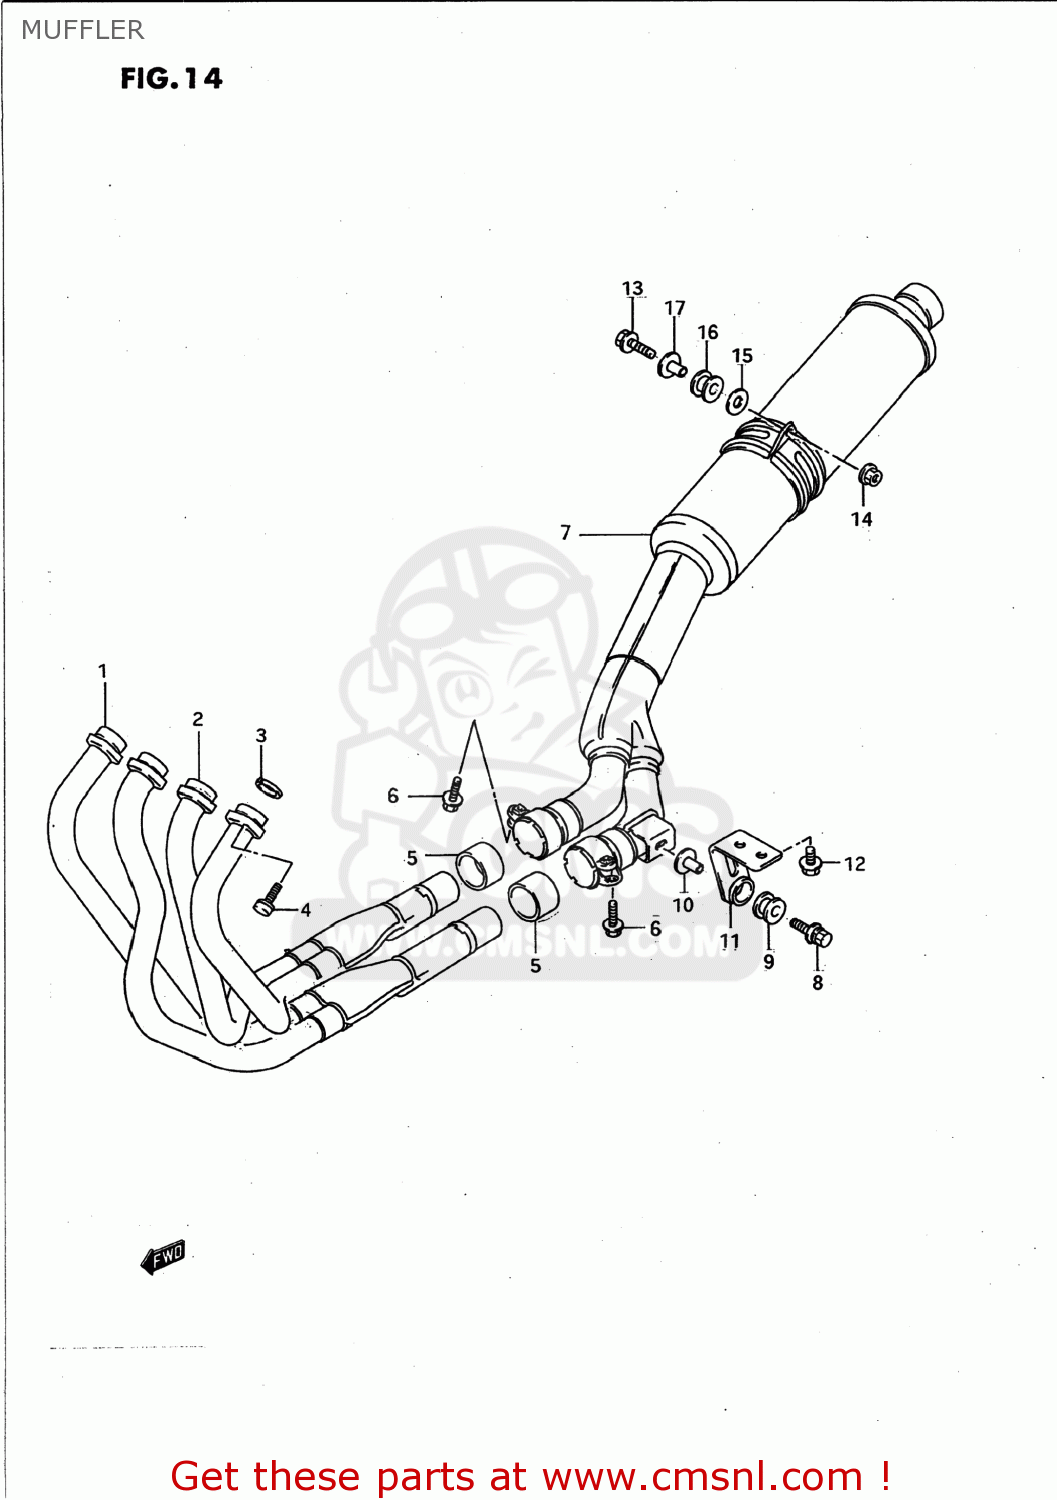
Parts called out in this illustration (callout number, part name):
1	PIPE,EXHAUST,RIGHT
2	EXHAUST,LEFT
3	GASKET,EXHAUST PIPE
4	BOLT
5	CONNECTOR,MUFFLER
6	BOLT
7	MUFFLER ASSEMBLY
8	BOLT
9	CUSHION
10	SPACER(8.6X12X24.2)
11	DAMPER,MUFFLER SUPPORT,FRONT
12	BOLT
13	BOLT
14	NUT
15	WASHER (8.1X33X1.6)
16	CUSHION
17	SPACER(8.6X12X27.1)
